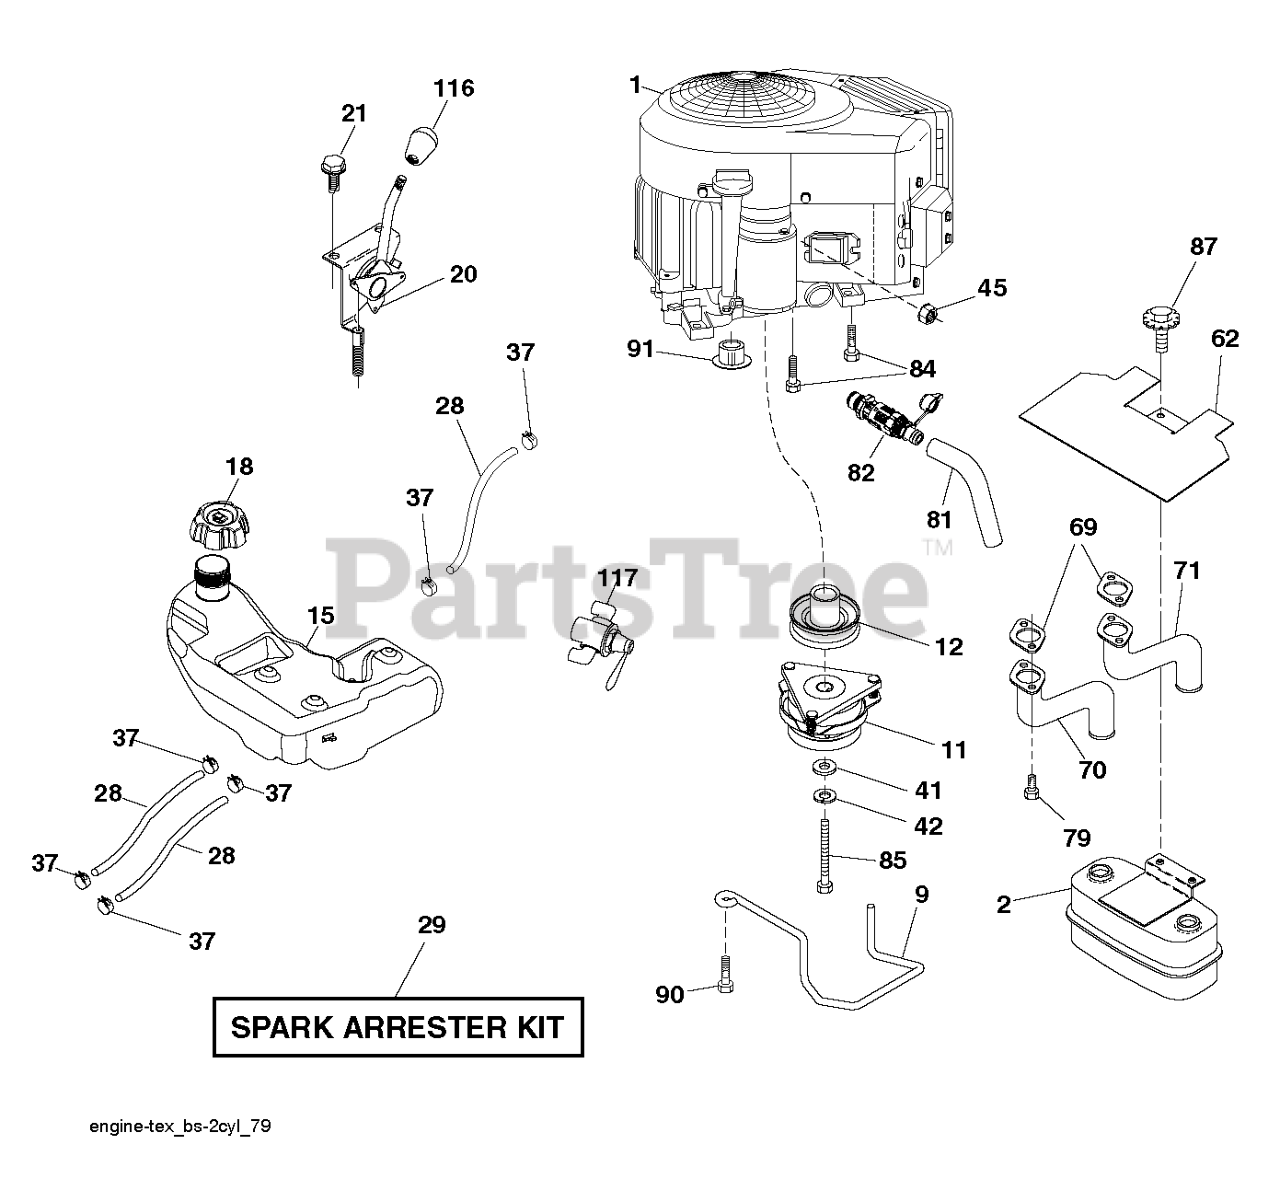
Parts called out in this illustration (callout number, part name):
2	MUFFLER.ASM.TWN.EXTNDED.DFLCTR
9	KEEPER BELT ENGINE
11	CLUTCH MZ ZTR GT.48/54"1.125"
12	PULLEY ENGINE
15	RP_TANK.ASSY.4.GAL.2.PORT.EPA
18	CAP.ASM.FL.RITCH.3"E10.SYM.498
20	CONTROL.THROTTLE/CHOKE.PRO.45
21	SCREW.#10 X 0.750.BOS
28	LINE.FUEL.64"REAR.EMIS
29	KIT.SPARK ARRESTOR 794945 B&S
37	HOSE CLAMP
42	LOCKWASHER
45	NUT
62	SHIELD.HEAT.MUFFLER
69	GASKET.MUFFLER
70	EXHAUST.TUBE.LH.BS/TWIN
71	EXHAUST.TUBE.RH.B&S.TWIN.INTEK
79	SCREW.SOCKET.HEAD.5/16-18
81	TUBE, DRAIN OIL ASM.
82	VALUE.OIL.DRAIN
84	SCREW.3/8-16
85	BOLT HEX 7/16-20 X 3.75 GR. 5
87	BOLT.5/16-18UNCX3/4 W/SEMS.BLK
90	SCREW 3/8-16X1
91	BUSHING.1.375OD
116	KNOB - SHIFT
117	VALVE FUEL RESERVE
